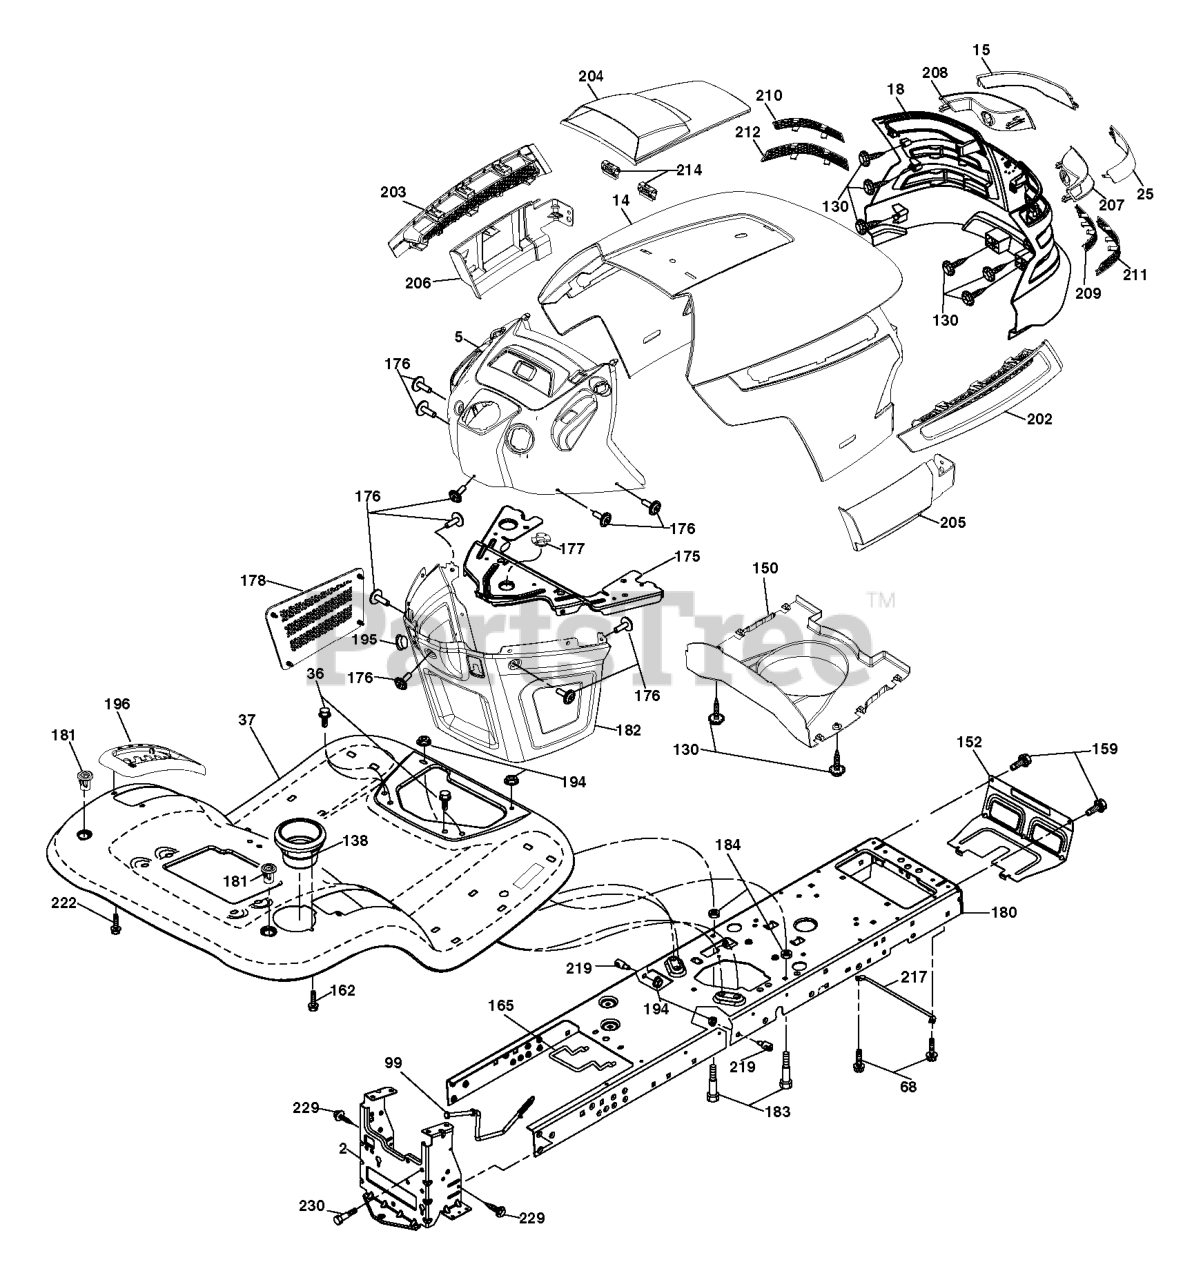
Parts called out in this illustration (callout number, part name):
2	DRAWBAR.1PC.NSTL
5	DASH.HUSQ.UPR.ELE.SVMD
14	HOOD.PNT.HUSQVARNA.GT.
15	LENS.LH.TEX.GT.HUSQ.CL
18	GRILLE.ASM.TEX.GT.HUSQ
25	LENS.RH.TEX.GT.HUSQ.CL
36	SCREW 5/16"
37	FEND/FTRST.PCH.CPH.NFW
68	Screw Thdrol 5/16-18 x 1/2
99	ROD.BYPASS.ASM.0510.HY
130	SCREW
138	CUPHOLDER.TL.TEX.418
150	AIR.DUCT.TEXGT.HUSQ.SV
152	SHIELD.BROWNING/DEBRIS
159	SCREW, 3/8-16X3/4
162	SCREW.HI-LO.CONSOLE
165	SUPPORT.TANK.REAR.WIRE
175	PLATE.CROSSMEMBER.HUSQ
176	SCREW.#10-24X5/8.RN.QU
177	BUSHING, STEERING
178	CARGO.ASM.NET.TXGT.W/C
180	CHASSIS.STAMPING.LT/GT
181	BUSHING.MNT.FEND.CRGO.
182	DASH.LOWER.COMMON.12V.
183	BOLT.5/16-18X1-1/4 FULL.THREAD
184	SPACER.FENDER
194	NUT LOCK HEX FLANGE 5/16-18
195	PLUG.HOLE.DASH.LOWER.12V.BLK
196	CONSOLE.ASM.DECK.LIFT.
202	VENT.SIDE.HOOD.HUSQ.RH.GREY
203	VENT.SIDE.HOOD.HUSQ.LH.GRAY
204	VENT.TOP.HOOD.HUSQVARN
205	SKIRT.HOOD.SIDE.HUSQ.RH.GREY
206	SKIRT.HOOD.SIDE.HUSQ.LH.GREY
207	BEZEL.RH.TEX.GT.HUSQ
208	BEZEL.LH.TEX.GT.HUSQ
209	INSERT.HEX.GRILL.HUSQ.GREY
210	INSERT.HEX.GRILL.HUSQ.
211	INSERT.HEX.GRILL.HUSQ.
212	INSERT.HEX.GRILL.HUSQ.
214	CLIP.RETAINER.TINNER.
217	ROD PIVOT CHASSIS/HOOD
219	STUD.FASTNER.W/ANTI-ROTATE
222	SCREW.1/4-20X5/8
229	SCREW 3/8-16X1
230	SHOULDER BOLT 5/16-18TT
